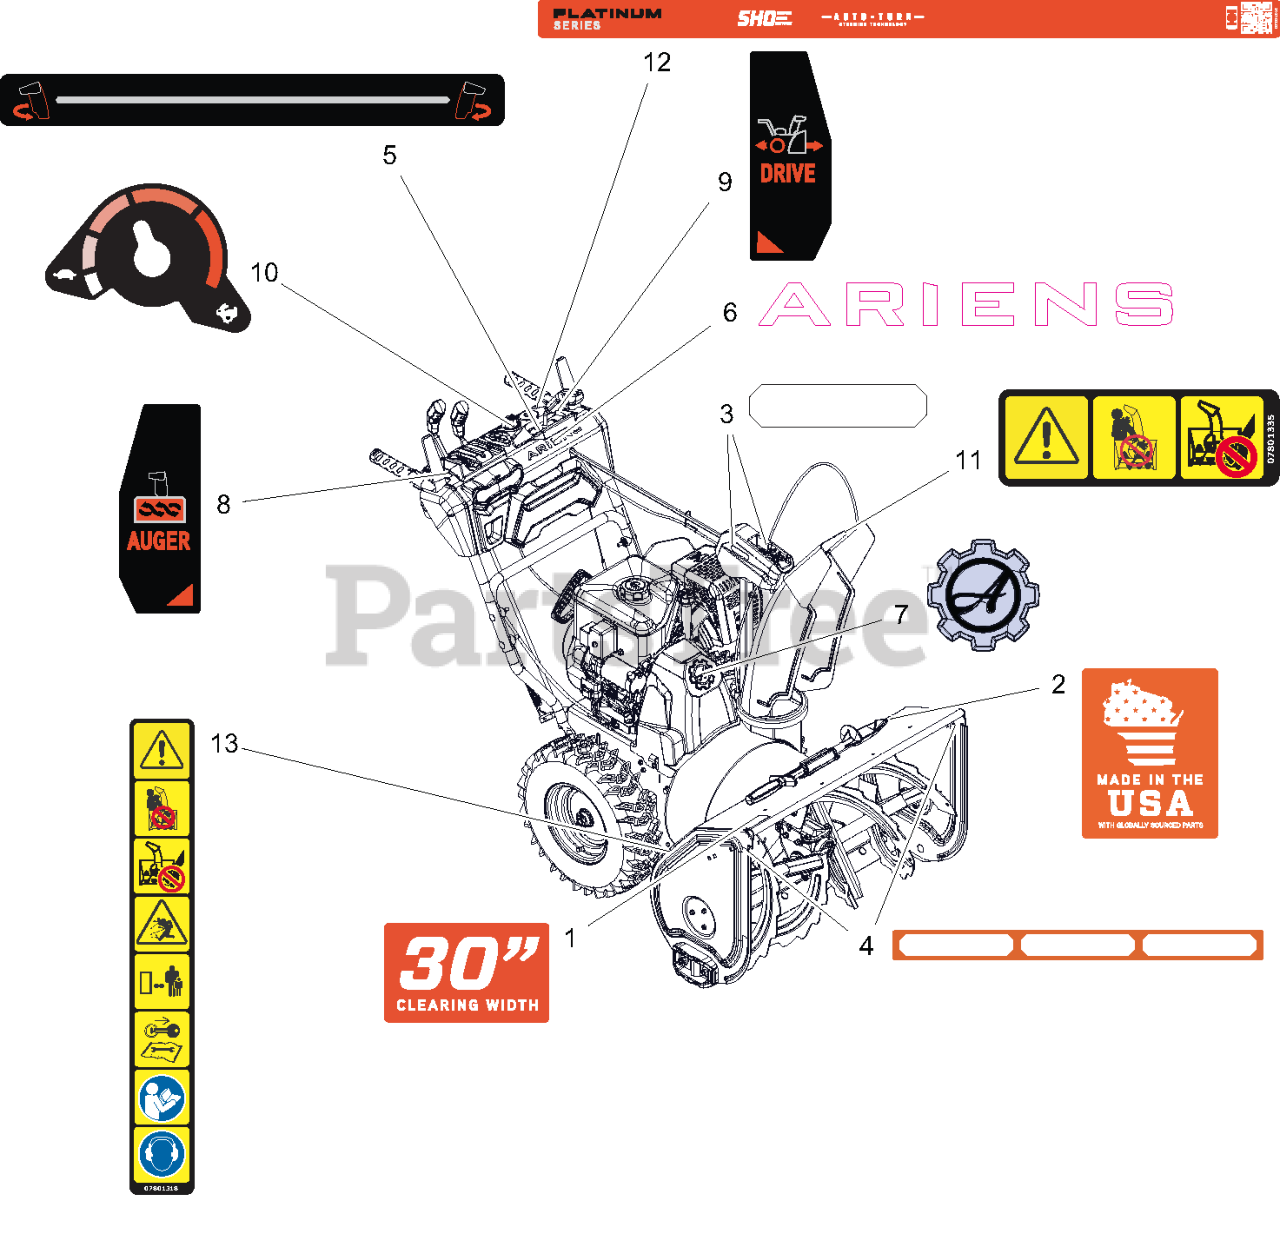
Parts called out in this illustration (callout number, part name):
1	DECAL- CLEARING - 30
2	DECAL- MADE IN USA
3	DECAL,REFLECTIVE,GEAR COVER
4	DECAL,REFLECTIVE,HOUSING
5	DECAL- CHUTE ROTATION
6	DECAL- ARIENS - 7.46"
7	DECAL- ARIENS GEAR BADGE
8	DECAL- CONTROL - AUGER
9	DECAL- CONTROL - DRIVE WHEEL
10	DECAL- CONTROL - EFI SPEED
11	DECAL- DANGER
12	DECAL, DASH - PLT EFI
13	DECAL- SAFETY - DANGER
